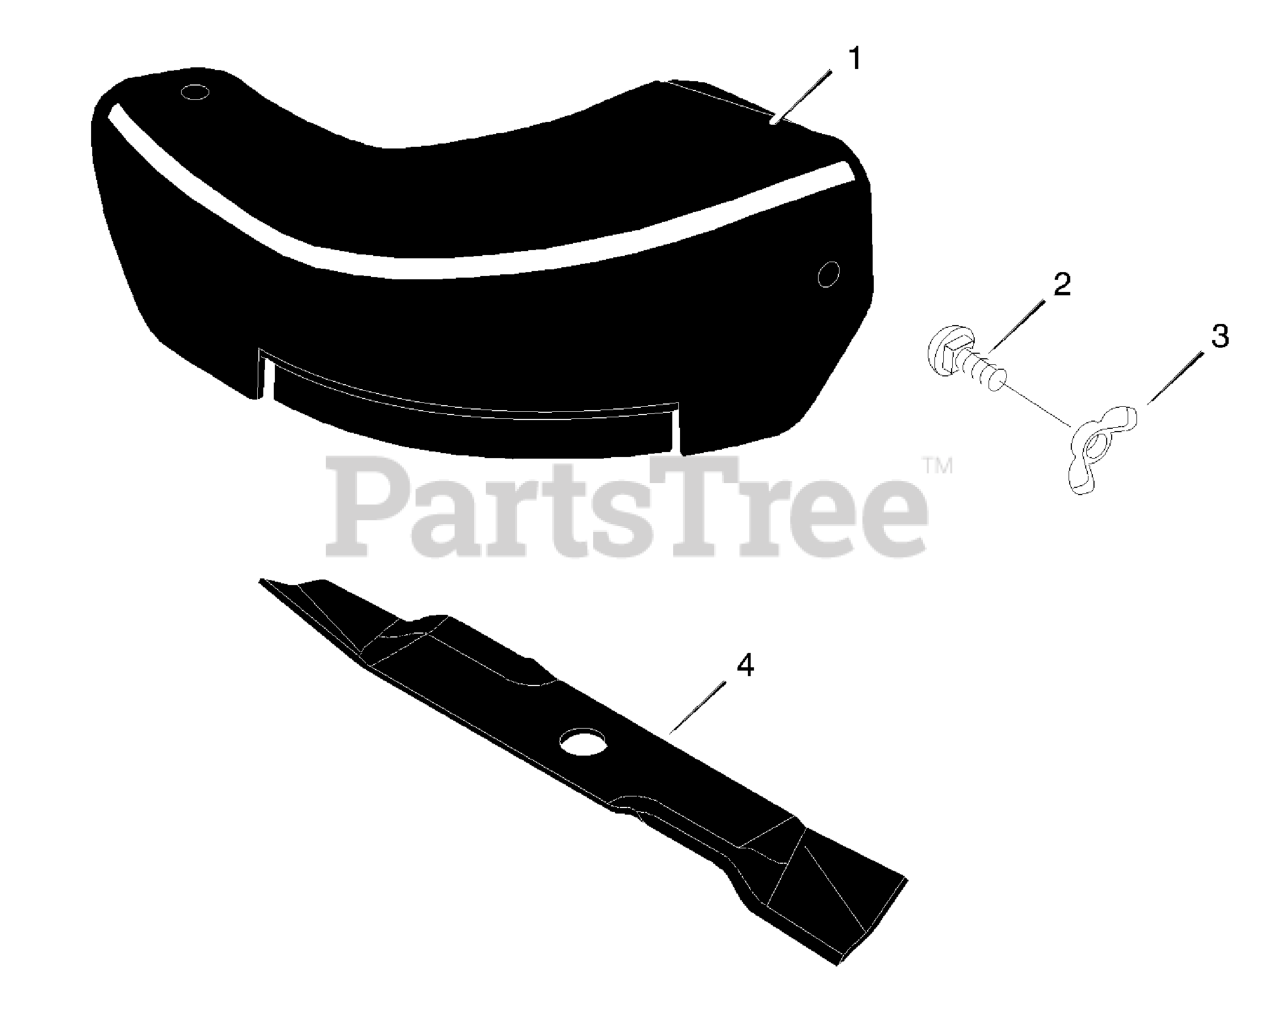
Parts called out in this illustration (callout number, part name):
1	Mulcher Plate
2	Carriage Bolt
3	Wingnut
4	Mulcher Blade
